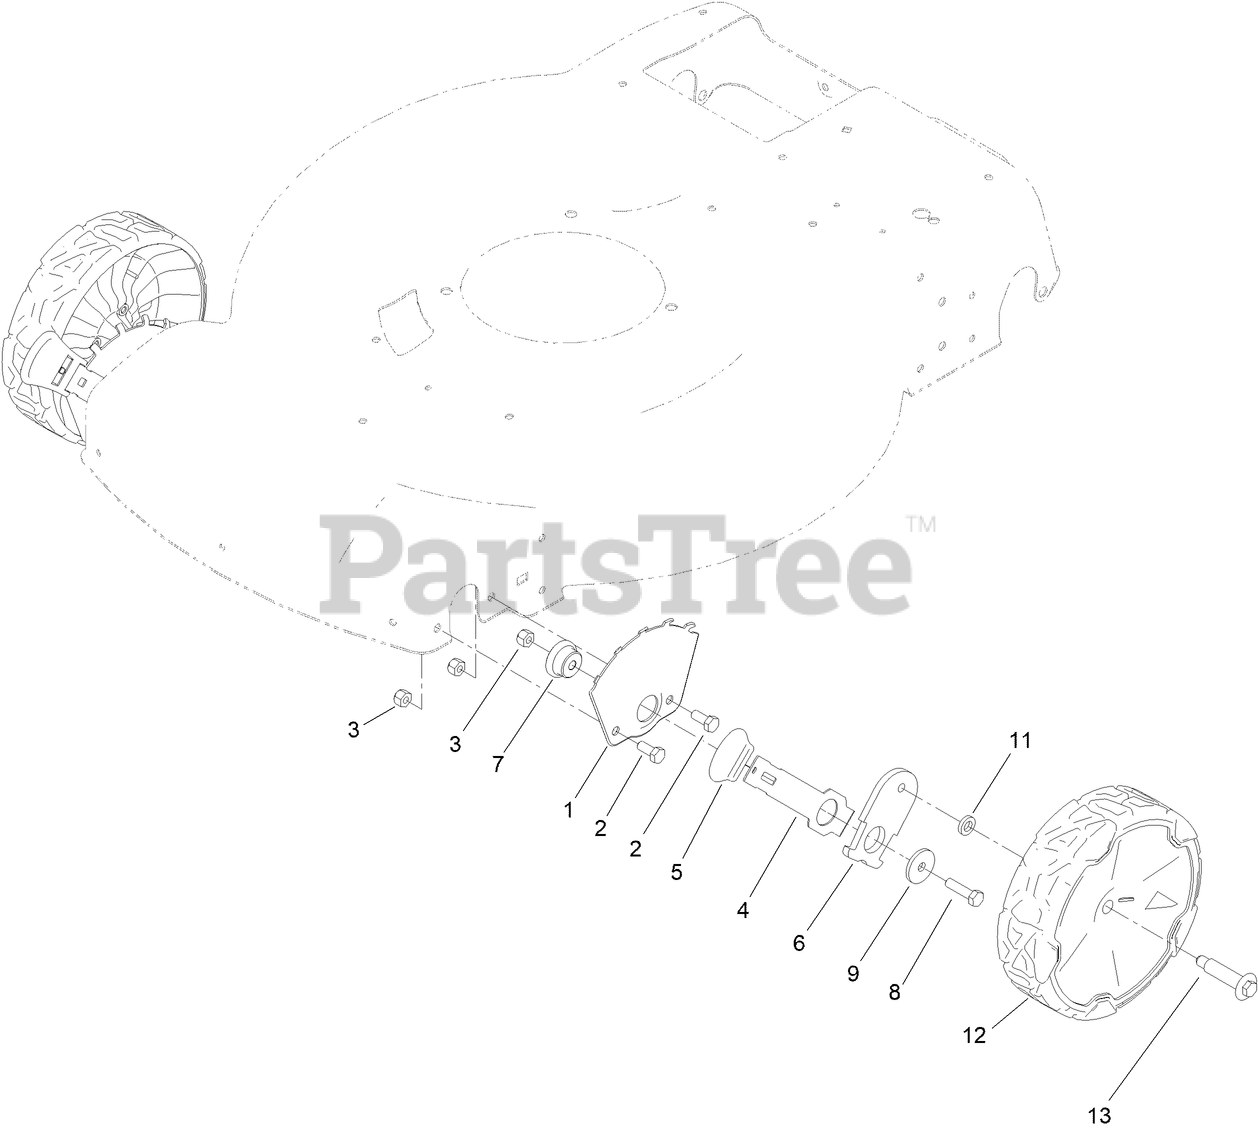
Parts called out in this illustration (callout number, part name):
1	PLATE-HOC,FRONT FSVQ WEDNESDAY
2	SCREW-HH
3	NUT-LOCK, NI
4	ARM-SPRING
5	KNOB-HOC
6	ARM-PIVOT, FRONT
7	BUSHING-MOUNT, HOC
8	SCREW-HH
9	WASHER-FLAT
11	WASHER-WHEEL BOLT
12	ASM-8" WHEEL, IDLER
13	WHEEL BOLT
